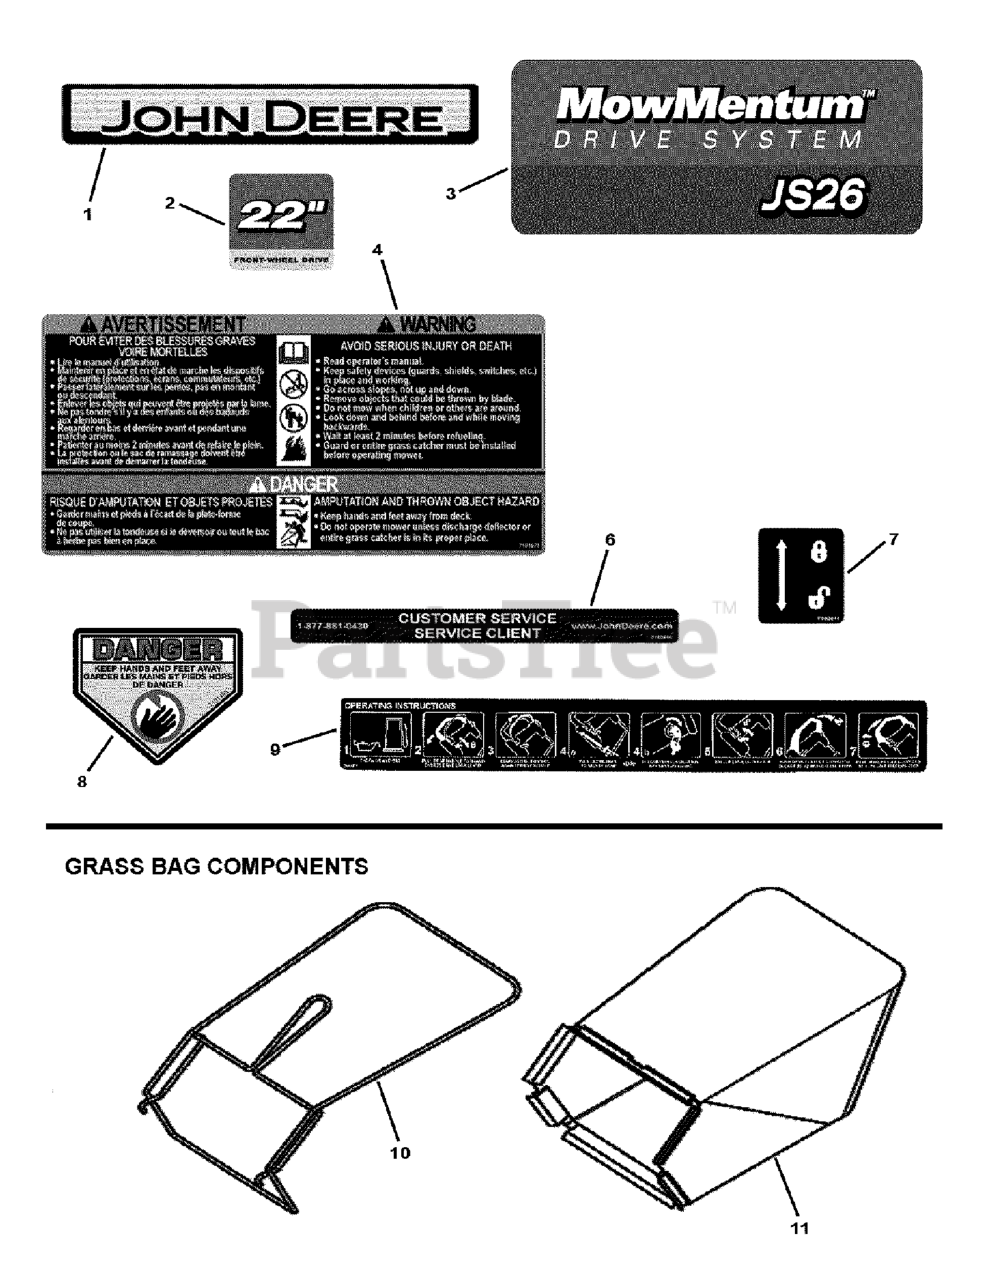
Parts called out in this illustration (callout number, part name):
1	DECAL, FRONT, JOHN DEERE, JS26
2	DECAL, 22" FRONT WHEEL DRIVE
3	DECAL, JS26 MOWMENTUM
4	DECAL, WB SAFETY, FRENCH/ENGLISH
6	DECAL, CUSTOMER SERVICE, FRENCH
7	DECAL, NEUTRAL LOCK, FC
8	DECAL, CPSC, FRENCH/ENGLISH
9	DECAL, OPERATION, JD
10	BAG FRAME, RD
11	BAG, GRASS, 22" REAR DISCHARGE
